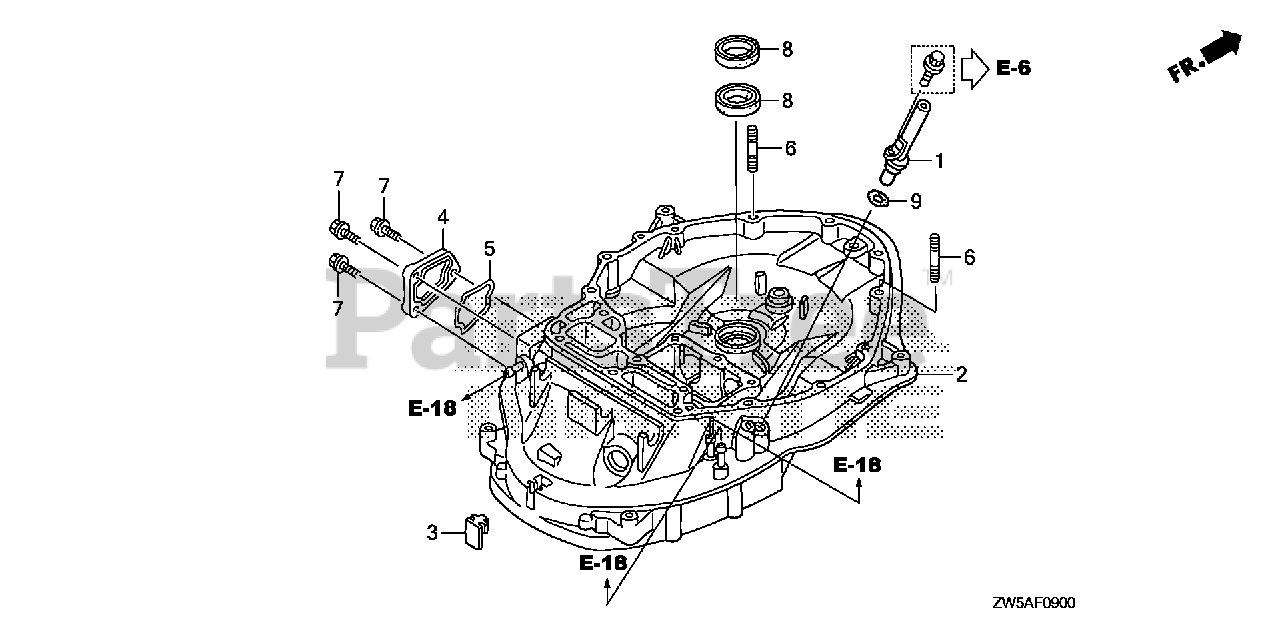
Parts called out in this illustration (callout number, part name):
1	PIPE, OIL LEVEL
2	CASE, MOUNT *NH8* (DARK GRAY)
3	RUBBER, MOUNT CASE SEAL
4	COVER, MOUNT CASE
4	COVER, MOUNT CASE *NH8* (DARK GRAY)
5	GASKET, MOUNT CASE COVER
6	BOLT, STUD (10X35)
7	BOLT, FLANGE (6X20)
8	SEAL, WATER (22X35X7)
9	O-RING (11.5X3.5)
